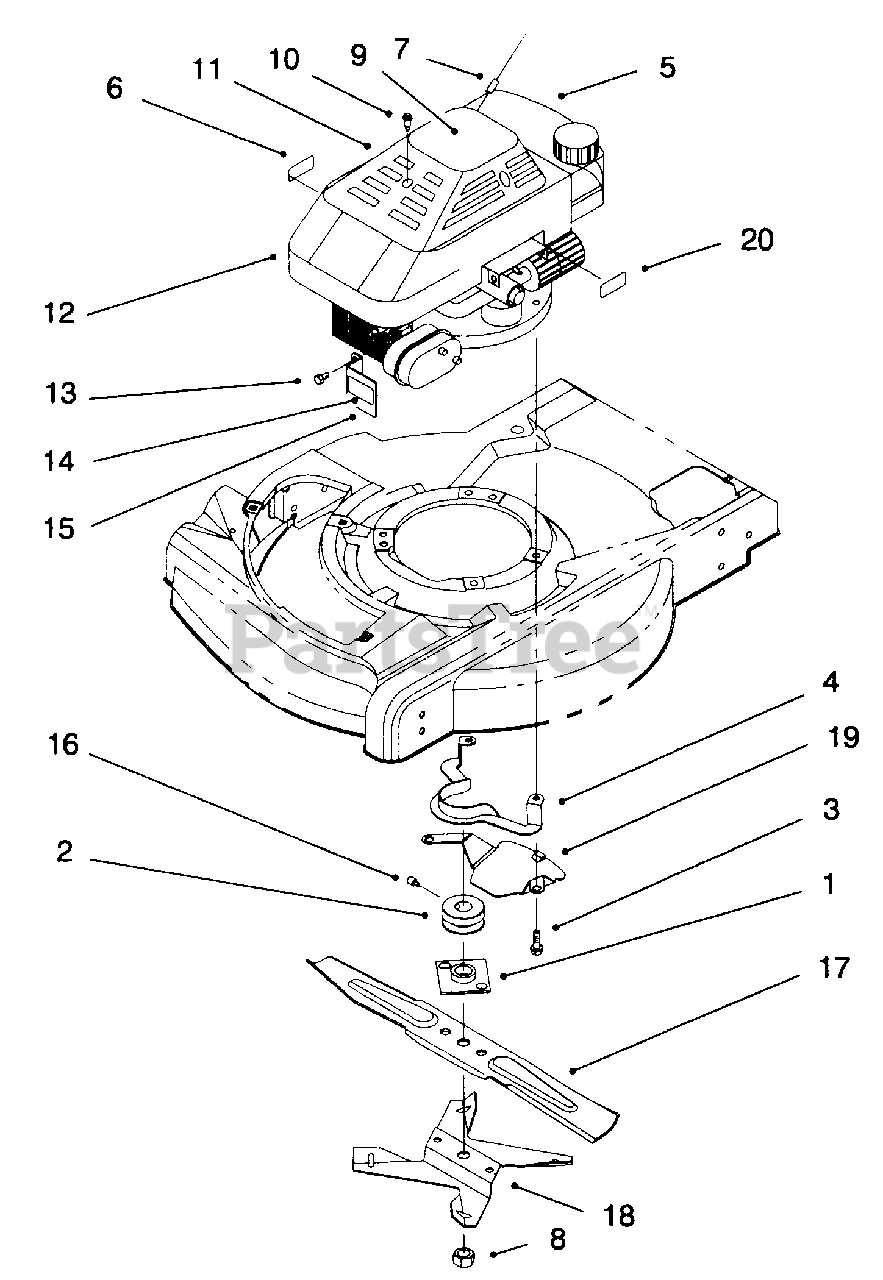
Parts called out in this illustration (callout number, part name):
1	Plate & Collar Assembly
2	Pulley-Engine
3	Screw-Engine
4	Guide-Belt
5	Engine
6	Decal-Oil Instruction
7	Rope-Stop
8	Nut-Blade
9	Decal-Recoil
10	Screw-Recoil Cover
11	Cover-Starter
12	Shroud-Engine
13	Screw-Hex Socket Hd.
14	Decal-Warning
15	Guard-Muffler (Incl. Ref. #14)
16	Screw-Set
17	Blade-21 " Whirl
18	Fan-Mulching
19	Shield-Grass
20	Decal-Primer
